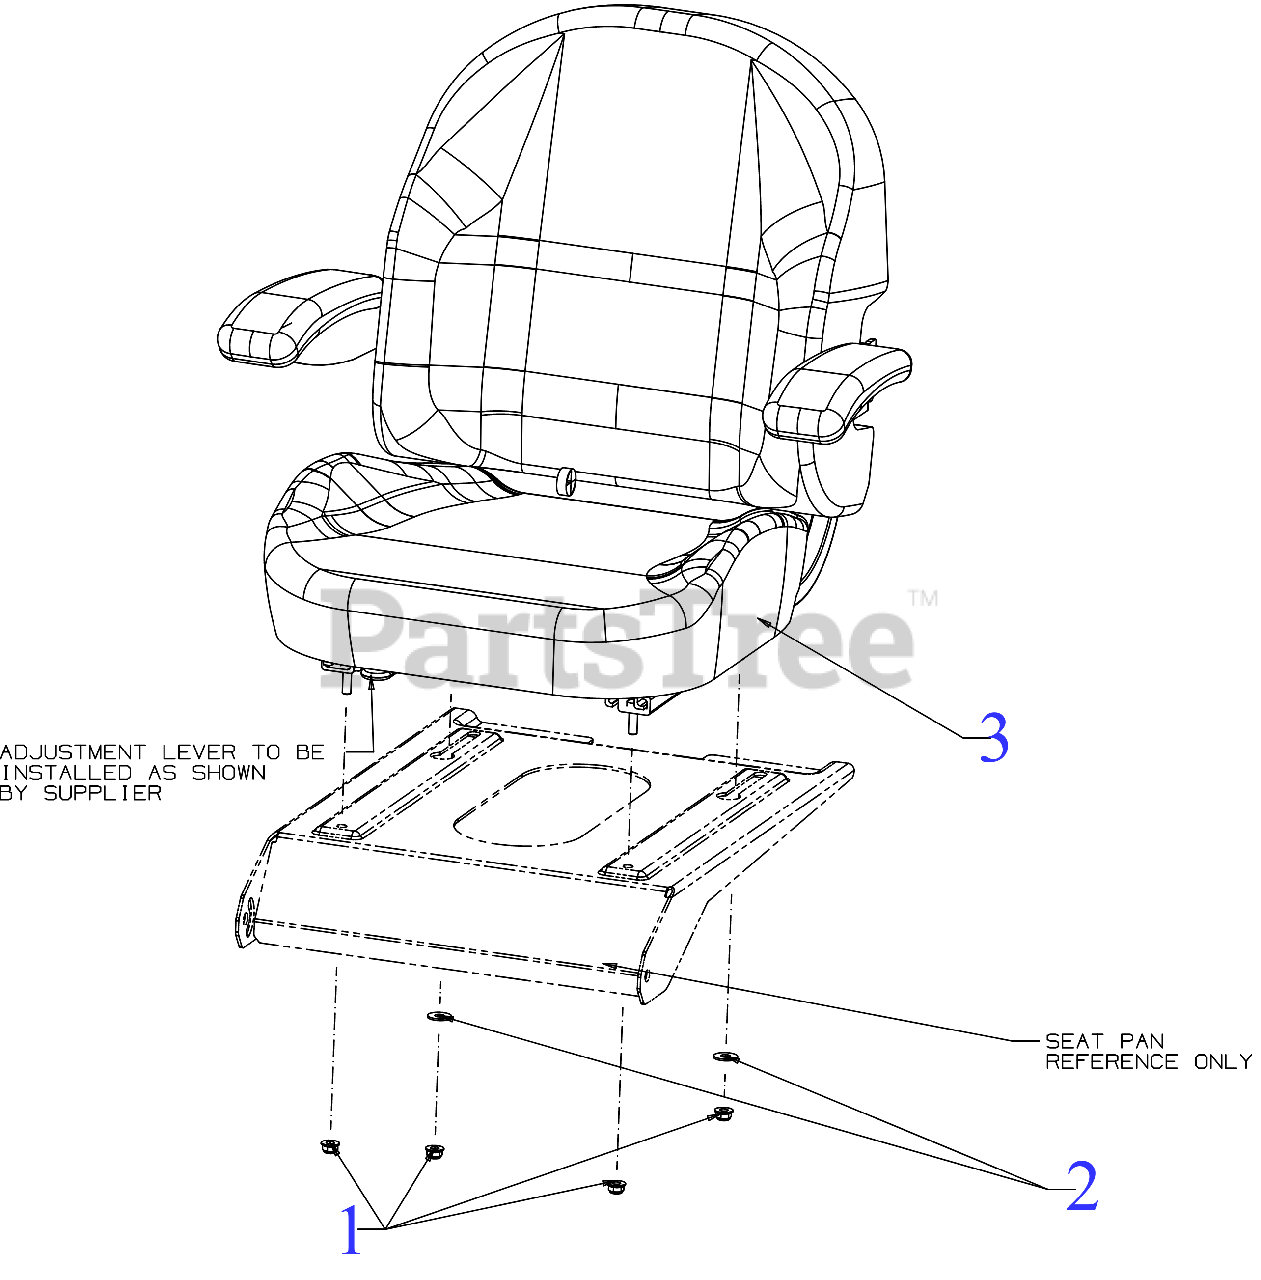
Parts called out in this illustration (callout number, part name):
1	FLANGE LOCK NUT 5/16-18
2	FLAT WASHER
3	SEAT (CUB SLIDE/ARM REST)
